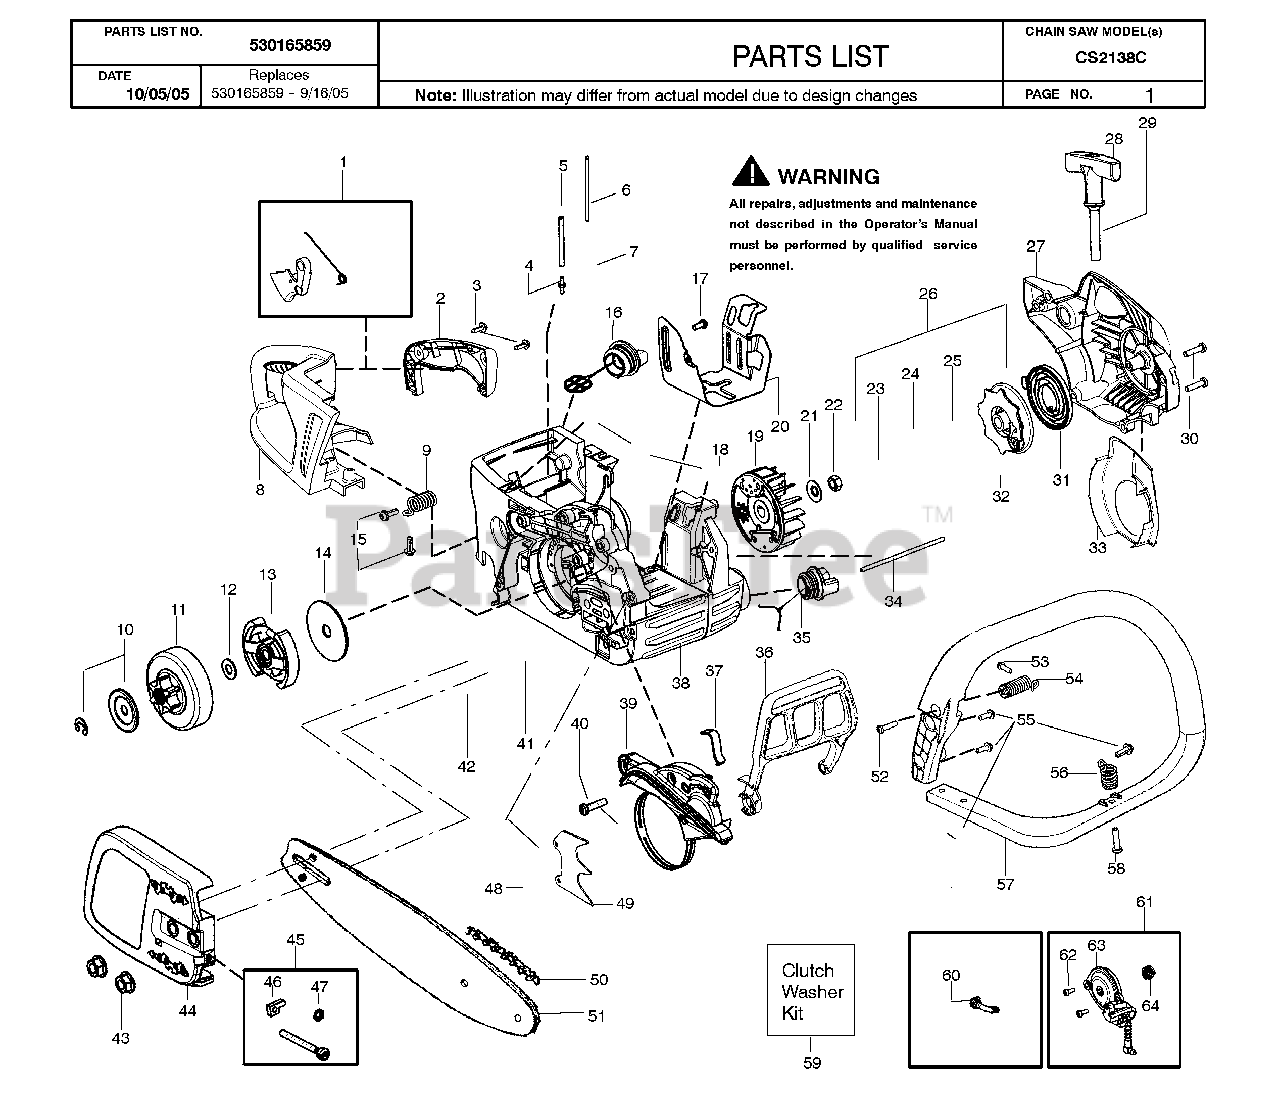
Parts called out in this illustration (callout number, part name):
1	KIT SAV TRIGGER & LOCKOUT
4	FUEL LINE FITTING
7	FUEL PICK-UP ASSY
9	SPRING ISOLATOR
10	KIT SAS CLUTCH WASHER
11	ASSY CLUTCH DRUM 3/8
12	KIT SAS CLUTCH WASHER
13	ASSY CLUTCH
14	WASHER CLUTCH LARGE
15	SCREW,FRONT HBAR 36/41
16	TANK CAP
20	SHIELD HEAT
21	WASHER-FLYWHEEL
22	NUT-FLYWHEEL
23	SCREW SHOULDER
24	HUB STARTER EPS
25	SPRING EPS
26	KIT EPS STARTER
28	HANDLE STARTER
30	SCREW M5.38-14X22.225MM
31	SPRING STARTER
33	BAFFLE FLYWHEEL
34	ASSEMBLY-OIL-VENT
35	OIL TANK CAP
36	HANDGUARD CHAIN BRAKE
37	SPRING HANDGUARD
39	KIT CHAIN BRAKE
40	SCREW M5.38-14X22.225MM
42	PLATE BAR MOUNTING
46	ADJUST PIN,BAR 36/41
49	SPIKE 36/41
52	SCREW M5.38-14X22.225MM
53	M5.0X0.8X16 TT TRX SEMS
54	SPRING ISOLATOR ASSEMBLY
55	SCREW,FRONT HBAR 36/41
56	SPRING ISOLATOR ASSEMBLY
57	HANDLE FRONT
58	SCREW M5.38-14X22.225MM
59	KIT SAS CLUTCH WASHER
60	ASSY PICK UP OIL TANK
61	KIT OIL PUMP
63	ASSY OIL PUMP
64	WORM GEAR
